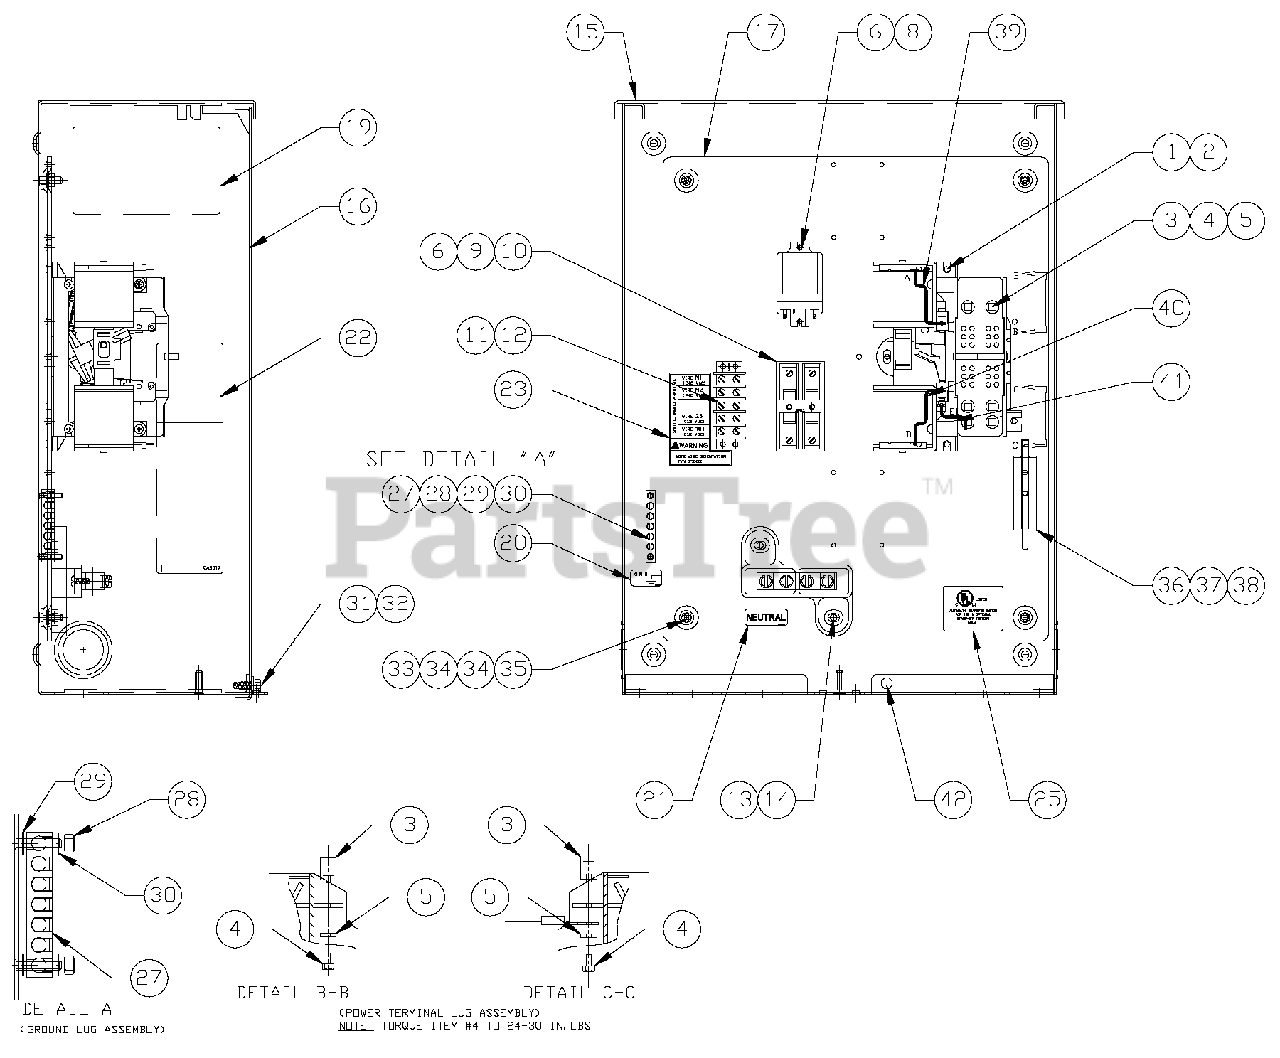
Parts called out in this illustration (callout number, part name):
1	TR SW-HSB 100A 2P 250V
2	SCREW HHTT M5-0.8 X 10 BP
3	LUG SLDLSS 1/0-#14X9/16 AL/CU
4	SCREW, PPHMS 10-32 X 3/8""
5	WASHER, LOCK # 10
6	SCREW PHTT M4-0.7 X 12 ZYC
8	RELAY PNL 12VDC DPDT
9	FUSEBLOCK 30A 600V 2 POLE
10	FUSE 5A X BUSS HLDR73591
11	BLOCK, TERM 20A 5 X 6
12	RIVET, POP .156 X .67
13	ASS’Y NEUTRAL BLOCK 100A
14	SCREW HHTT M6-1.0 X 12 MM
15	ENCLOSURE, 100/200A TRANSFER SWITCH
16	COVER, TRANSFER SWITCH
17	SUBPLATE, 100/200A XFER SW
18	DECAL, FRONT COVER ATS NEMA3R
19	DECAL, XFER SW NON 100A 120/240
20	DECAL, GROUNDING LUG
21	DECAL, NEUTRAL
22	DECAL, MANUAL 5A FUSE
23	DECAL, TERMINAL STRIP
24	DECAL, TEST SEQUENCE
25	DECAL, UL LIST HSB
26	DECAL, LIVE CIRCUIT ENG/FRN/SPN
27	GROUND BAR (5) 4-14 AWG CONN
28	NUT HEX LOCK M4-0.7 SS NYL INS
29	WASHER SHAKEPROOF EXT #8 STEEL
30	WASHER FLAT M4
31	SCREW HHC 1/4-20 X 1/2 SS
32	WASHER M6 NYLON INT HEX
33	NUT HEX 1/4-20 SS
34	WASHER FLAT 1/4-M6 ZINC
35	WASHER LOCK M6-1/4
36	BRACKET, ARM EXTENDER
37	ARM EXTENDER PIN
38	SCREW HWHS #6-25 X 3/8 ZNC
41	WIRE-E1
42	NUT TRIC 1/4-20 X .525
